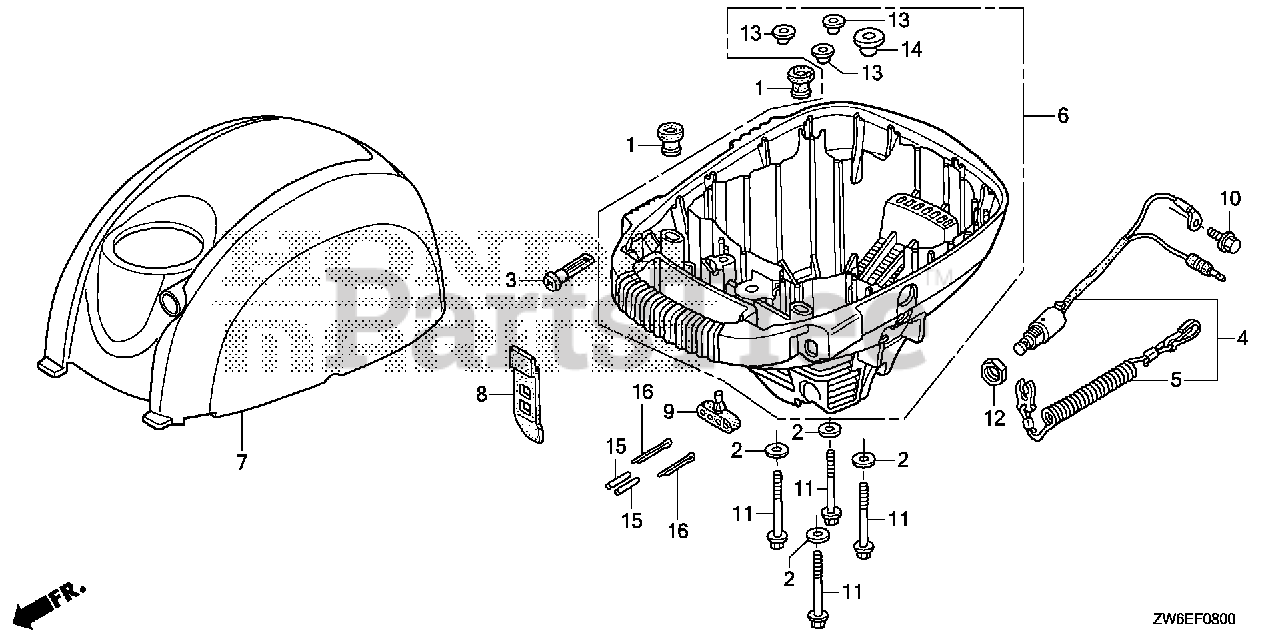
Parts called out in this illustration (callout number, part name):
1	RUBBER, TANK MOUNTING (C)
2	WASHER, PIVOT
3	KNOB, CHOKE
4	SWITCH ASSY., EMERGENCY STOP
5	WIRE, EMERGENCY
6	CASE, ENGINE (LOWER)
7	COVER, ENGINE *NHB14M* (AQUA MARINE SILVER METALLIC)
8	BELT, ENGINE COVER
9	HOLDER, PARTS
10	BOLT, FLANGE (5X10) (CT200)
11	BOLT, FLANGE (6X60)
12	NUT, HEX. (16MM)
13	COLLAR (6X4)
14	COLLAR, ENGINE CASE (LOWER)
15	PIN, SHEAR
16	PIN, SPLIT (3MM)
16	PIN, SPLIT (3.0)
